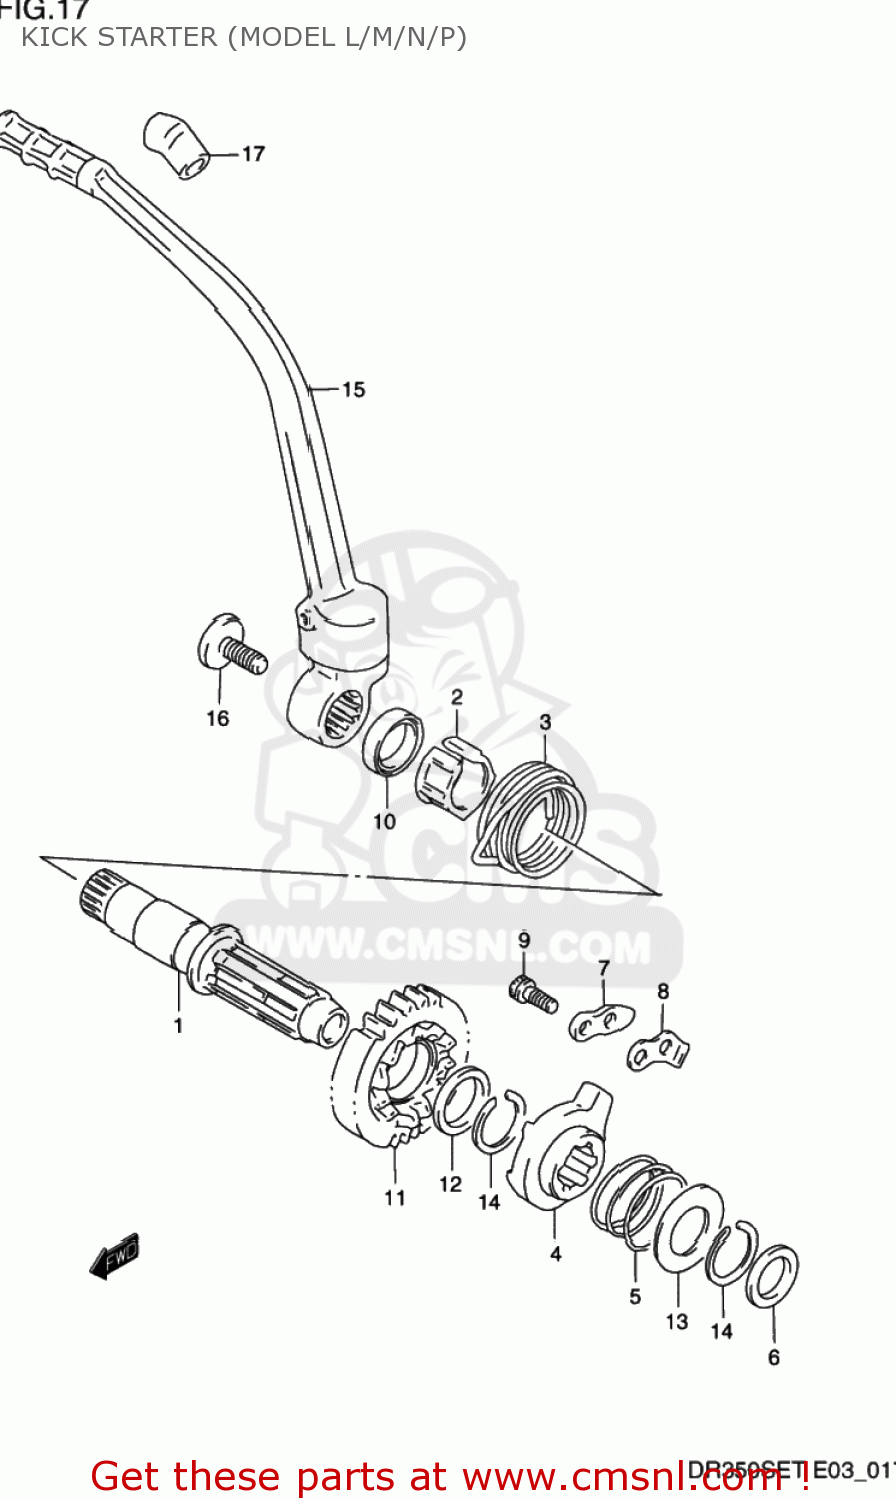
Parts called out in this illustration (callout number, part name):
1	SHAFT,KICK STARTER
2	GUIDE,KICK STARTER SFT SPRING
3	SPRING
4	STARTER,KICK
5	SPRING
6	WASHER,THRUST
7	GUIDE,KICK STARTER
8	STOPPER,KICK STARTER
9	BOLT,KICK START STOPPER
10	SEAL,OIL(20X27X6)
11	GEAR,KICK STARTER NO.2
12	SHIM
13	WASHER,THRUST
14	CIRCLIP
15	LEVER ASSEMBLY,KICK STARTER
16	BOLT(8X14)
17	COVER,KICK STARTER LEVER
